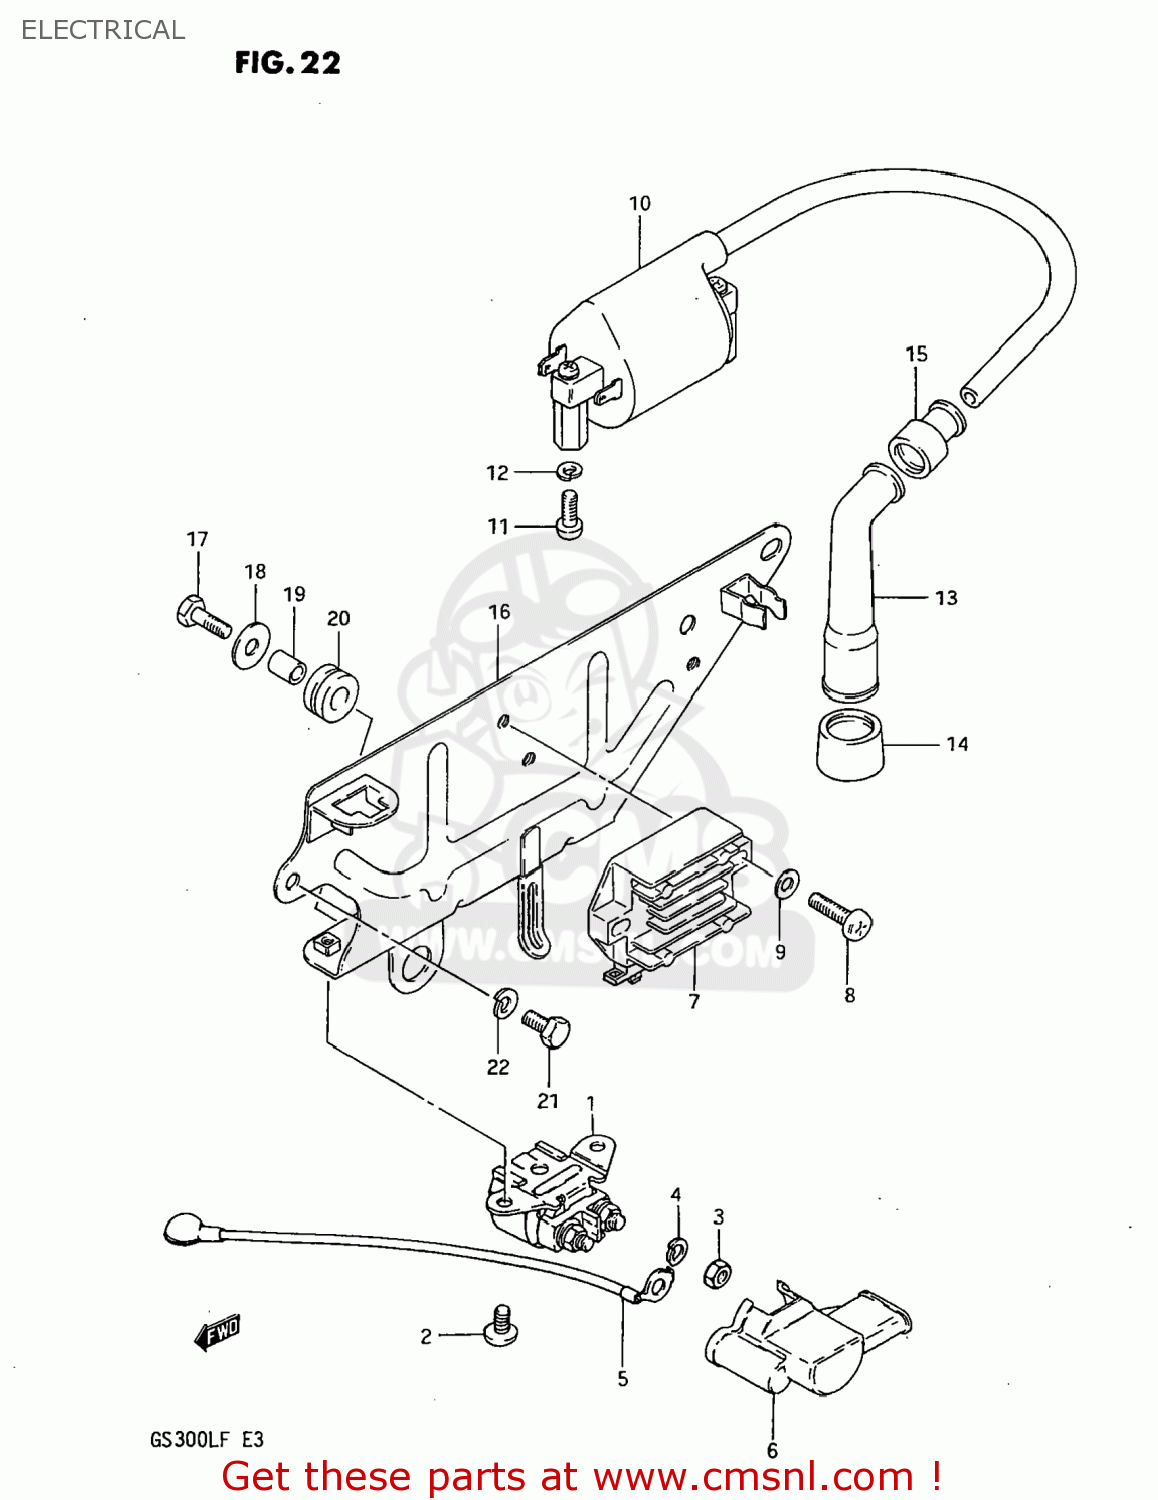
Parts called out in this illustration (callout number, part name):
1	RELAY ASSY,STARTING MOTOR
2	SCREW
3	NUT
4	WASHER,LOCK
5	WIRE,STARTER MOTOR LEAD
6	CAP,STARTER RELAY
7	RECTIFIER ASSEMBLY
8	SCREW
9	WASHER
10	COIL ASSY,IGNITION
11	SCREW
12	LOCK WASHER
13	CAP ASSY,SPARK PLUG
14	SEAL,SPARK PLUG CAP
15	SEAL,SPARK PLU
16	HOLDER COMP,ELECTRONIC PARTS
17	BOLT,M6X1X20
18	WASHER
19	SPACER (6.1X8X9.5)
20	CUSHION
21	BOLT
22	LOCK WASHER
